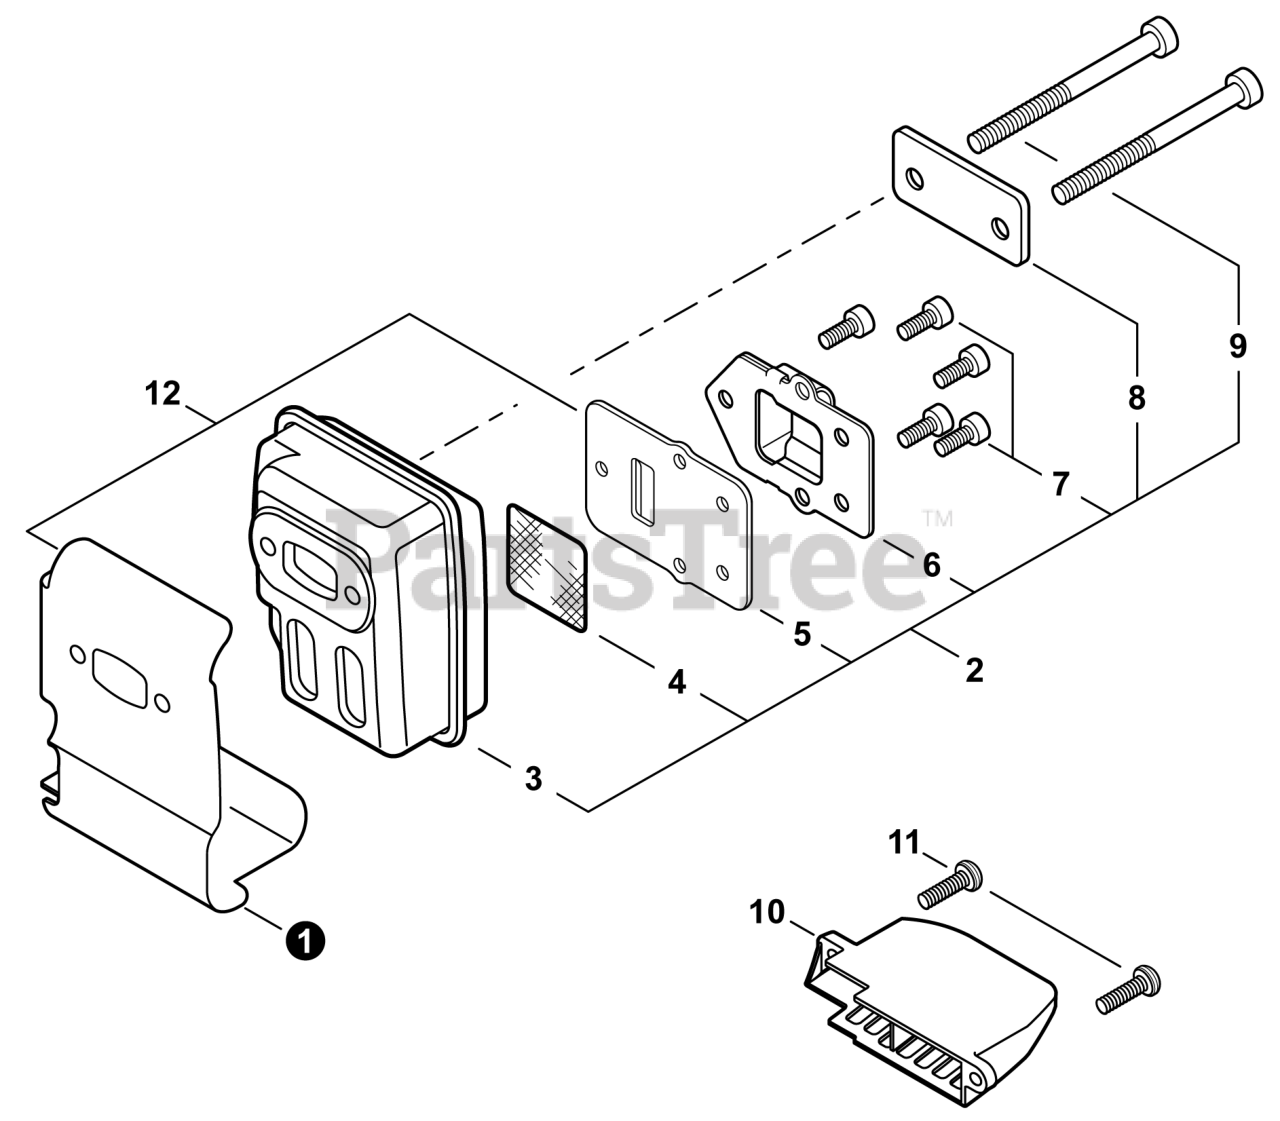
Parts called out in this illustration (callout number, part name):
1	HEAT SHIELD, EXHAUST
2	MUFFLER ASSY
3	MUFFLER
4	SCREEN, SPARK ARRESTER
5	GASKET, EXHAUST
6	GUIDE, EXHAUST
7	BOLT, TORX 4x8
8	PLATE, EYE
9	BOLT, TORX 5x55
10	COVER, MUFFLER
11	BOLT, TORX 5x16
12	GASKET KIT: ENGINE, INTAKE, EXHAUST
